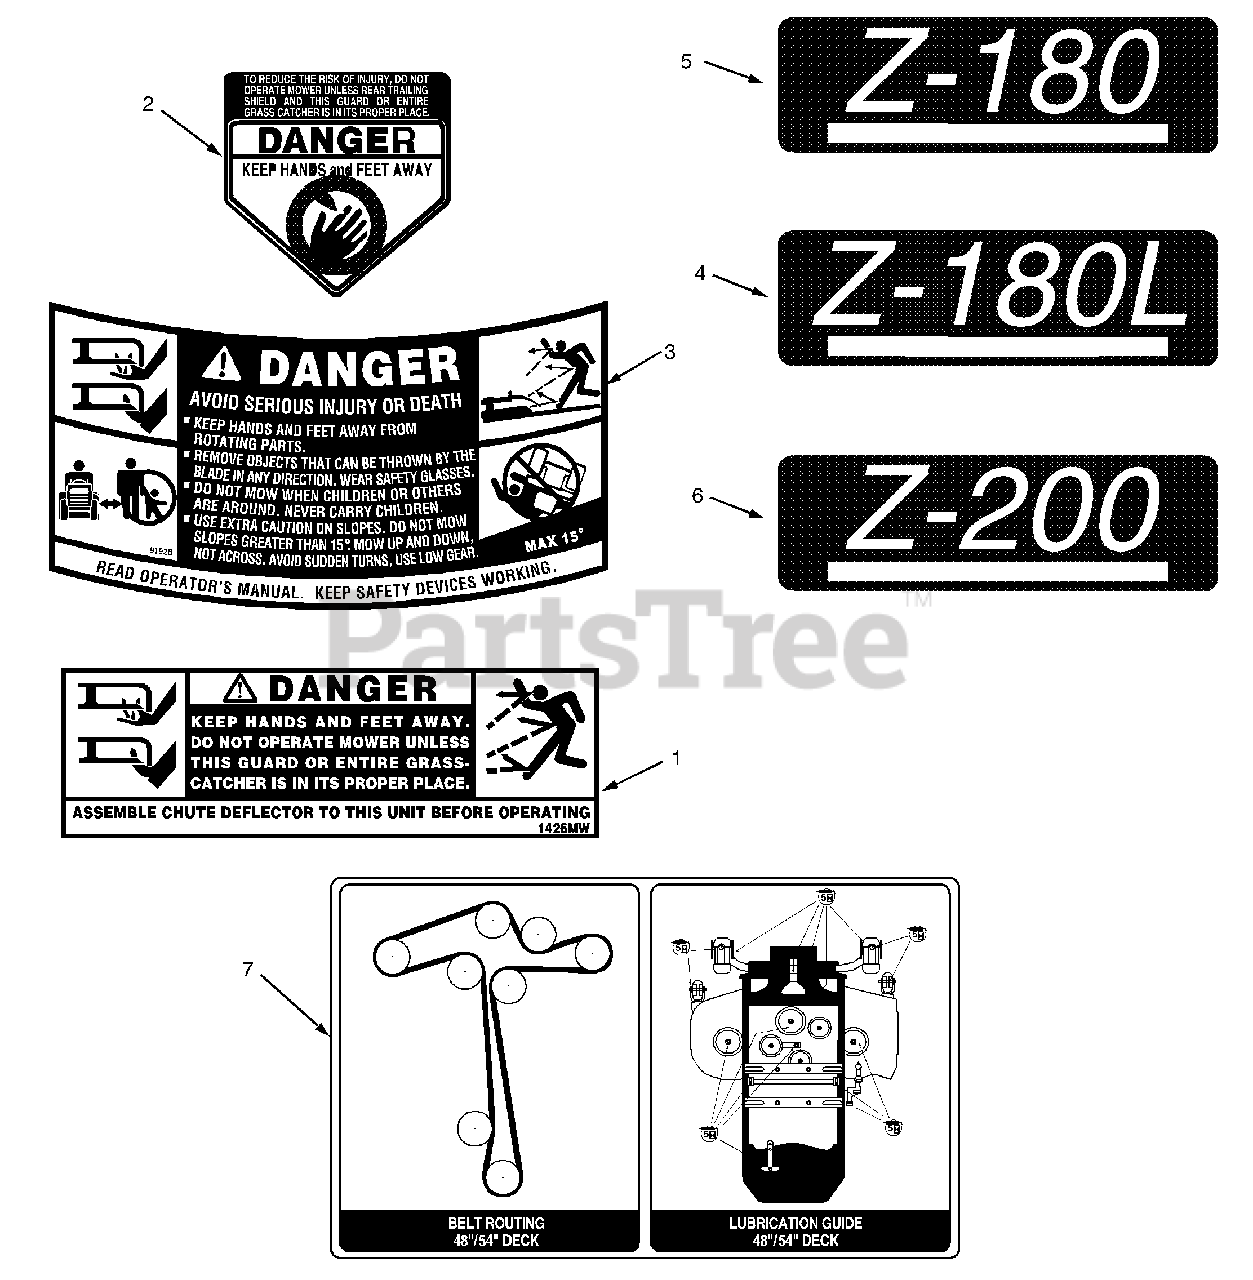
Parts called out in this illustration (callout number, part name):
1	Label, Danger - Top of Deck
2	Label, Danger - Top of Deflector Chute
3	Label, Safety - Top of Deck
4	Label, model - Front Steering Console
5	Label, model - Front Steering Console
6	Label, model - Front Steering Console
7	Label, Information - Under Belt Cover
